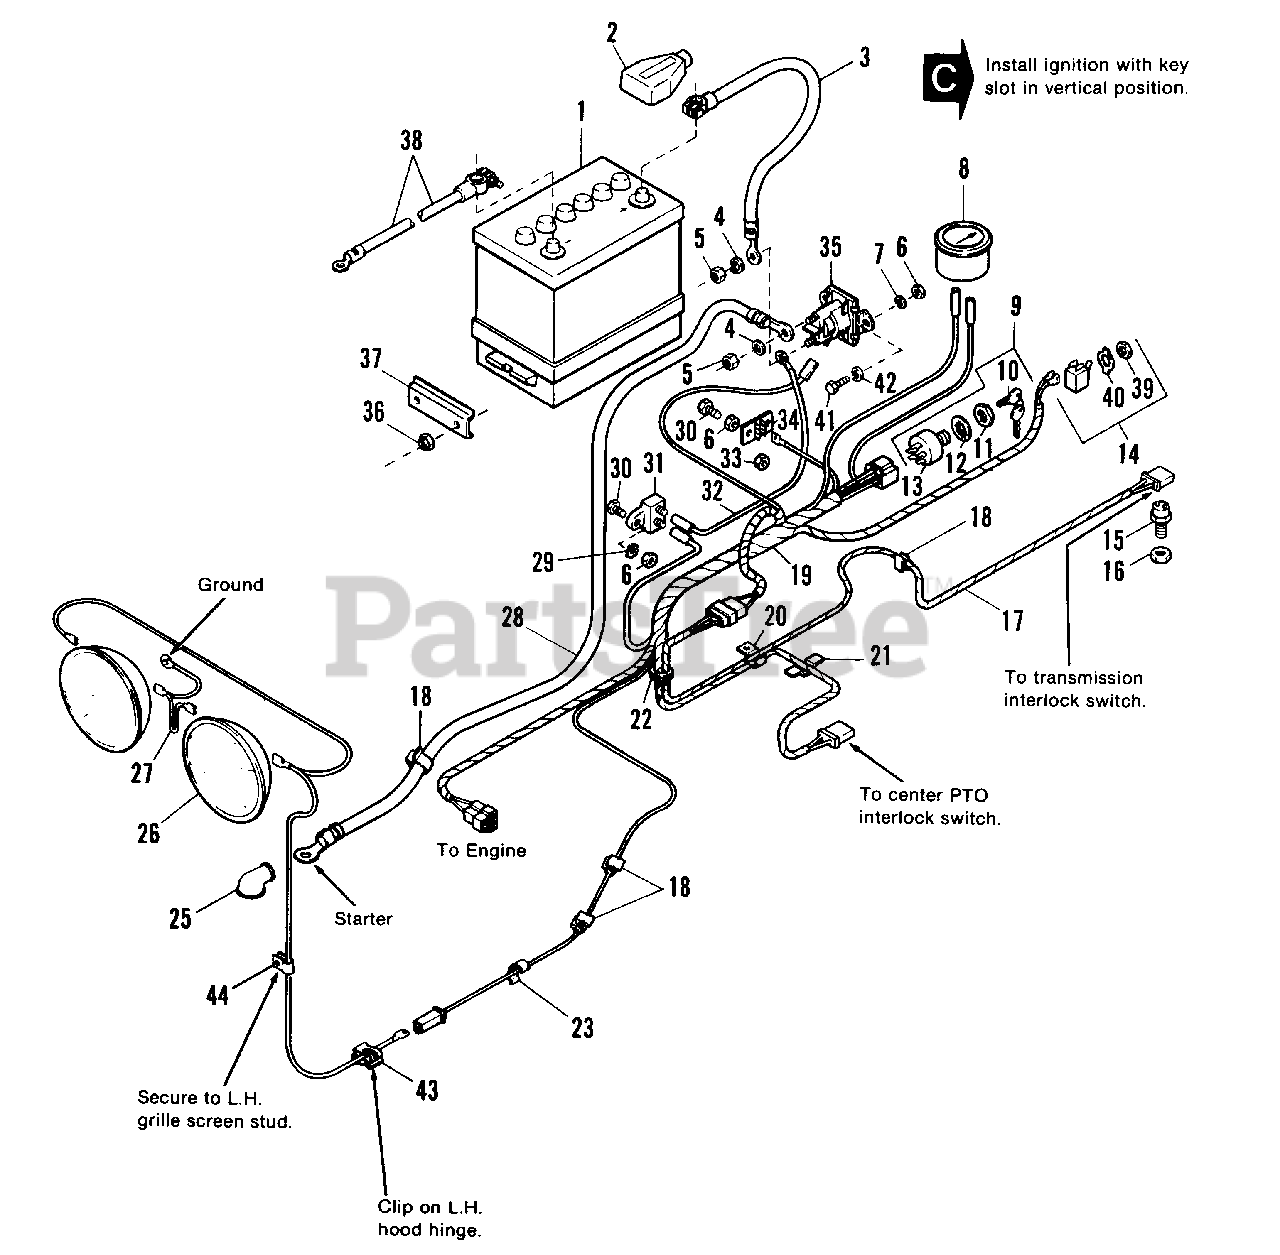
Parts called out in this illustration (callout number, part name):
1	BATTERY (Includes Decals)
2	PROTECTOR, Terminal
3	CABLE (Battery to Ground)
4	LOCKWASHER. 5/16
5	NUT, Hex, Full, 5/16-18
6	NUT, Hex, Full, 1/4-20
7	LOCKWASHER, 1/4 (Qty. 2 on 7114)
10	KEY SET (2)
11	NUT, Special
12	LOCKWASHER, Internal 5/8
14	SWITCH, Toggle
15	SWITCH, Interlock
16	NUT, Pal
17	WIRE ASSY.
18	CLIP, Tinnerman
19	HARNESS ASSY.
20	CLIP, Cable
21	CLIP, Wire
23	CLIP, Tinnerman
25	COVER, Terminal
26	LAMP, Sealed Beam, G.E., #4411-1
27	WIRE ASSY.
28	GABLE (Solenoid to Starter)
29	LOCKWASHER,1/4
30	CAPSCREW, Hex Hd., 1/4-20 x 5/8
31	CIRCUIT BREAKER
33	LOCKNUT, Hex, 1/4-20
34	BOARD, Terminal
35	SOLENOID, Starter
36	NUT, Elastic, 5/16-18
38	CABLE (Battery to Ground)
39	NUT, Switch
41	CAPSCREW, Hex Hd., 1/4-20 x 3/4
42	WASHER, Special
43	CLIP, Speed Cable
44	CLAMP, Wire
